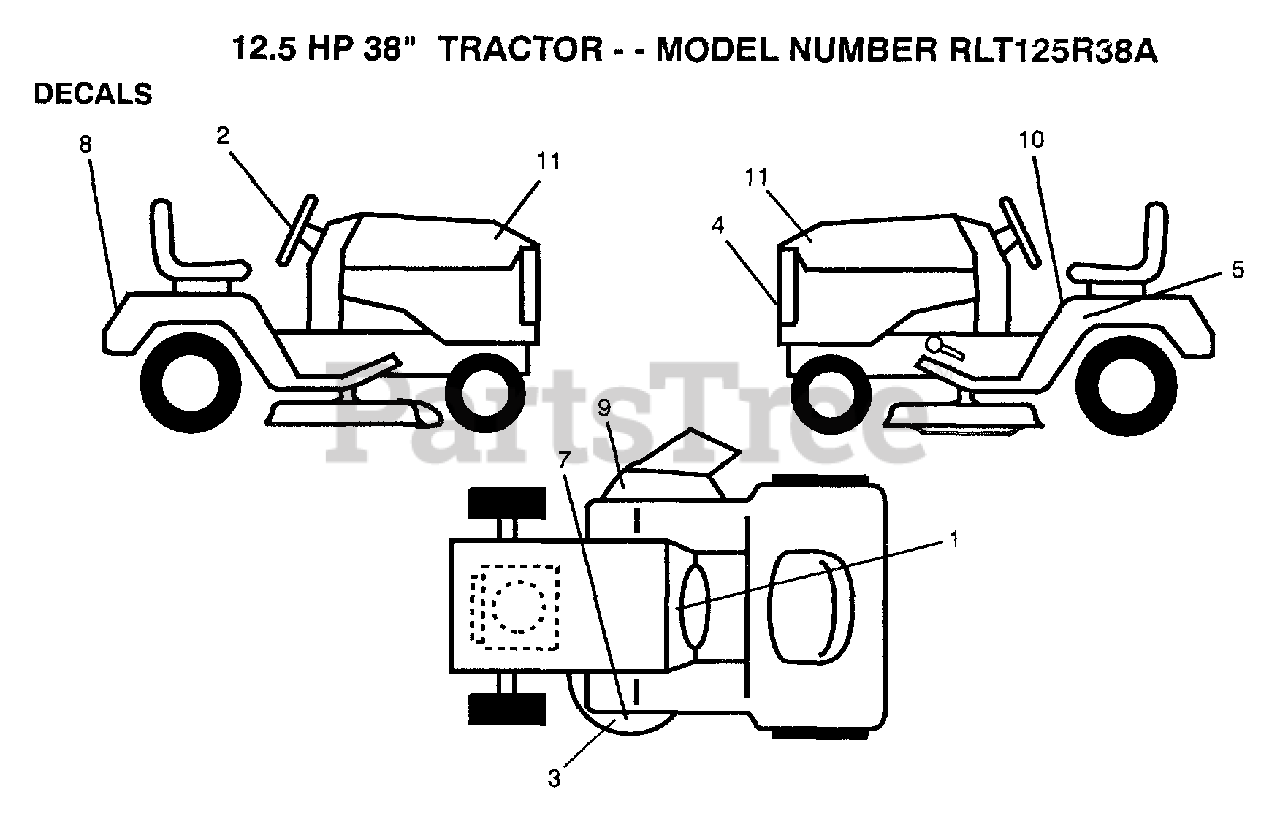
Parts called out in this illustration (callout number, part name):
2	"DECAL,STR WHL"
4	GRILL DECAL
5	IND HGT DECK DECA
7	DECAL YT
8	FENDER DECAL
9	DECAL WARNING
10	DECAL CAUTION
